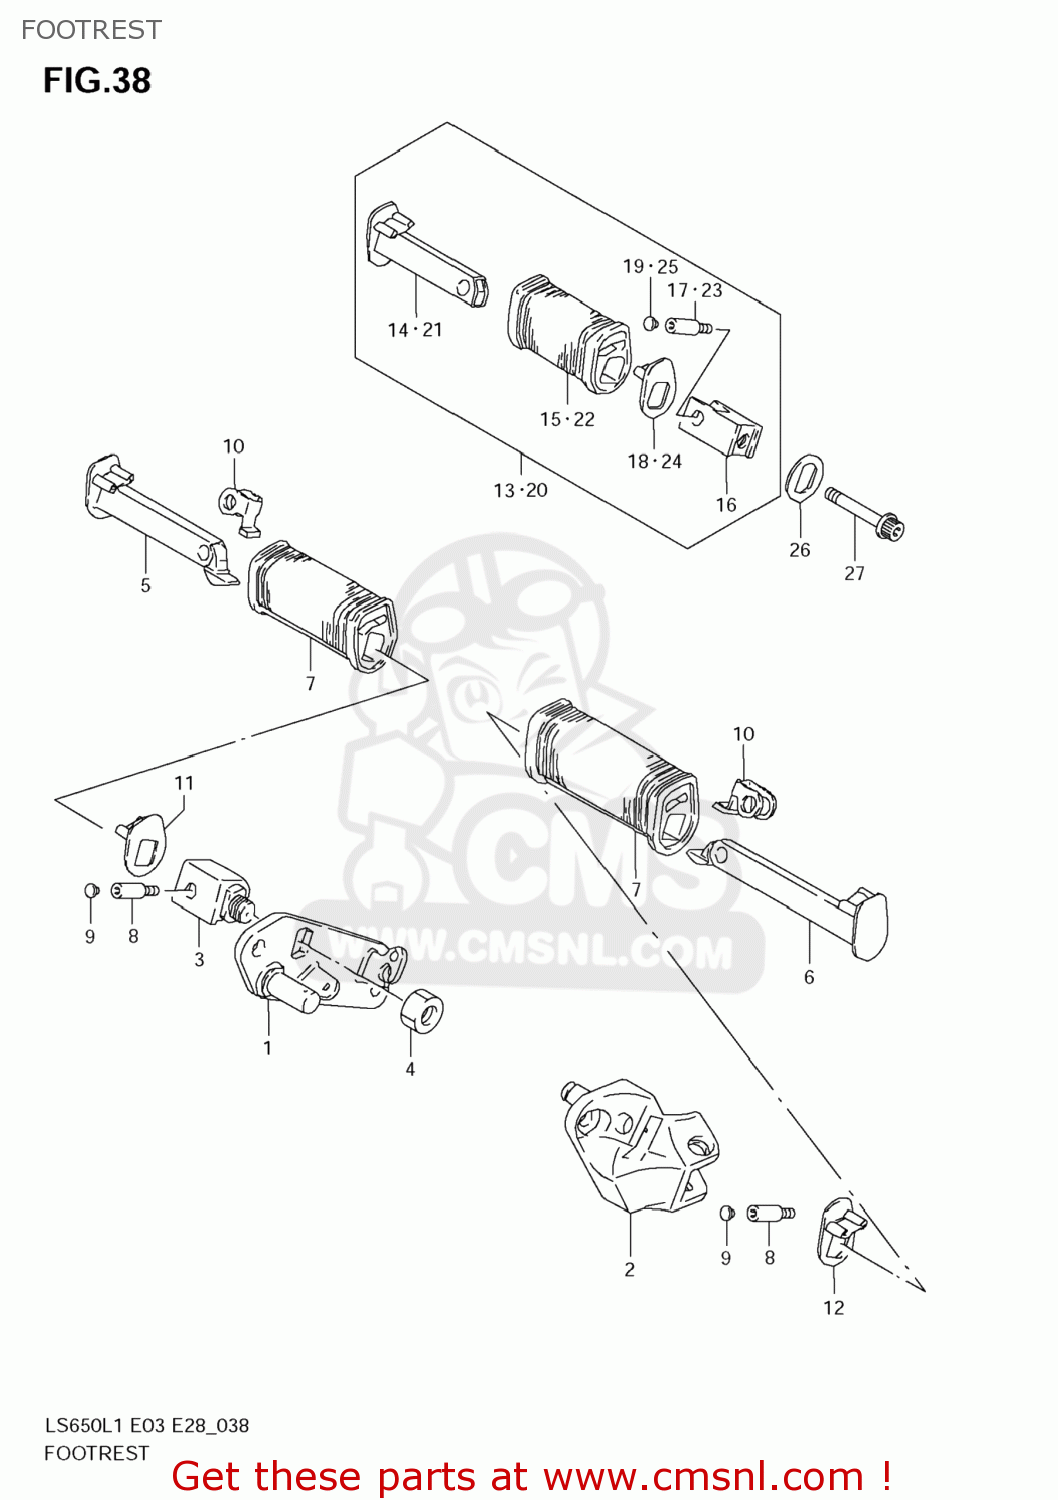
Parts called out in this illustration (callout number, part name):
1	BRACKET,FR FOOTREST,R
2	BRACKET,FR FOOTREST,L
3	HOLDER,FR FOOTREST,R
4	NUT
5	BAR,FR FOOTREST,R
6	BAR,FR FOOTREST,L
7	RUBBER,FR FOOTREST
8	BOLT(6X8)
9	CAP,PILLION FOOTREST BOLT
10	CUSHION,FR FOOTREST
11	WASHER,FR FOOTREST,R
12	WASHER,FR FOOTREST,L
13	FOOTREST ASSY,PILLION,R
14	BAR,PILLION FOOTREST,R
15	RUBBER,PILLION FOOTREST
16	HOLDER,PILLION FOOTREST
17	BOLT(6X8)
18	WASHER,FR FOOTREST,R
19	CAP,PILLION FOOTREST BOLT
20	FOOTREST ASSY,PILLION,L
21	BAR,PILLION FOOTREST,L
22	RUBBER,PILLION FOOTREST
23	BOLT(6X8)
24	WASHER,FR FOOTREST,L
25	CAP,PILLION FOOTREST BOLT
26	WASHER,PILLION FOOTREST HOLDER
27	BOLT(10X45)
